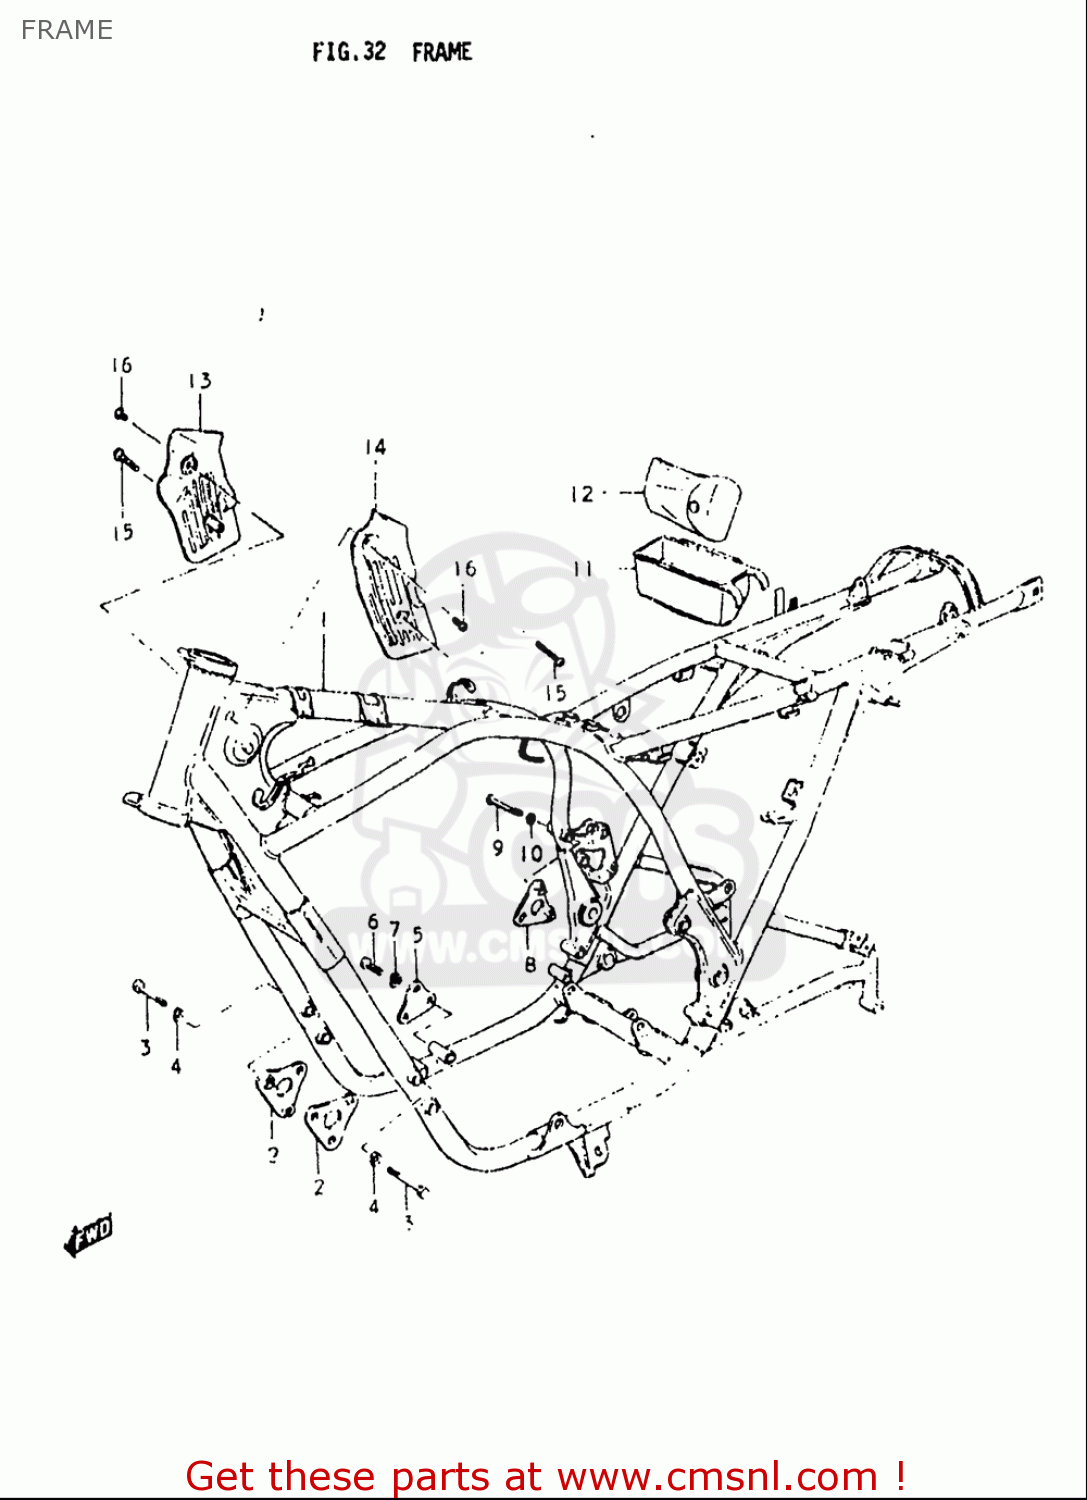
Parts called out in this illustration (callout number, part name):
3	BOLT
4	WASHER,LOCK
6	BOLT
7	WASHER,LOCK
9	BOLT
10	WASHER,LOCK
12	TOOL ASSY
15	SCREW
16	SCREW
